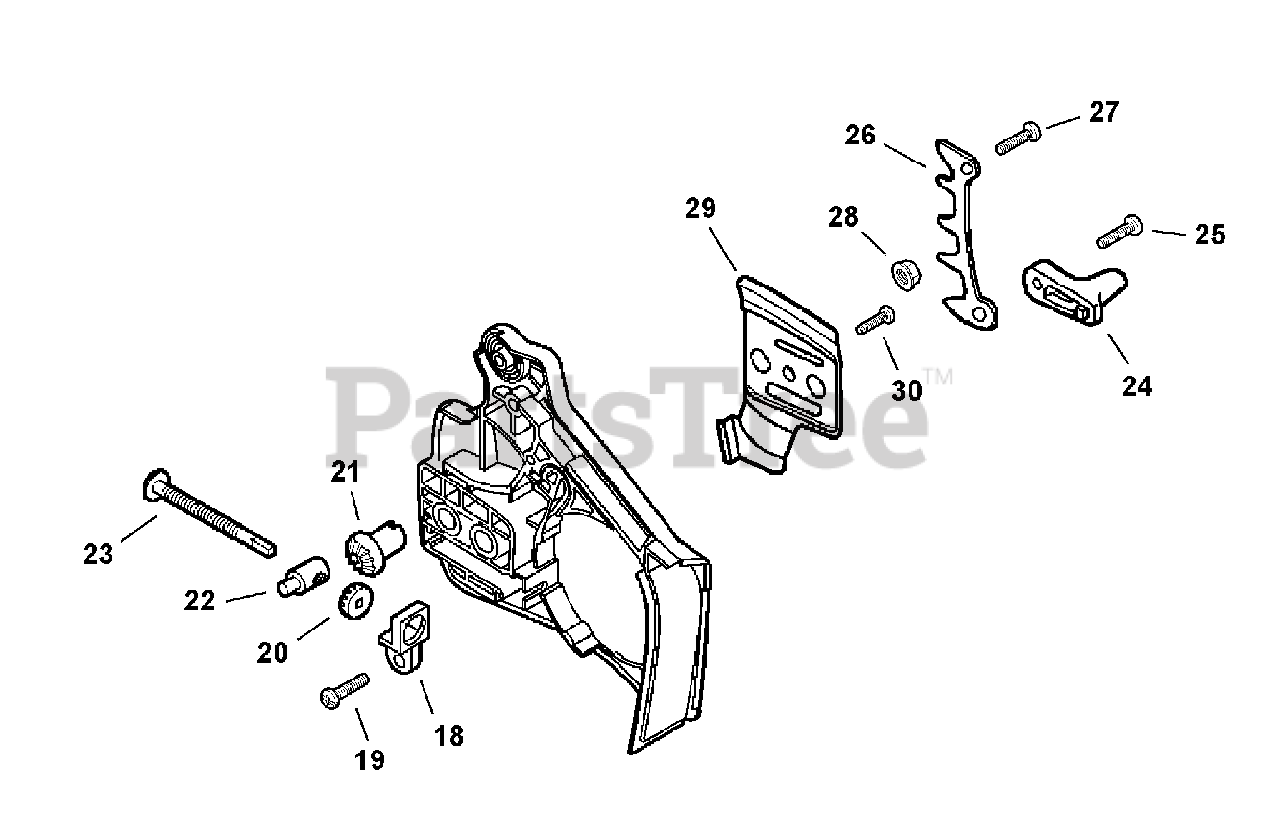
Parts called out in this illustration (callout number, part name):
18	COLLAR 8
19	SCREW 4×12
20	GEAR, BEVEL
21	GEAR, BEVEL
22	TENSIONER, CHAIN
24	CHAIN CATCHER
25	SCREW, TAPPING 5×20
26	SPIKE, BUMPER
27	SCREW, TAPPING 5×20
28	NUT, FLANGE M6
29	PLATE, GUIDE - INNER
30	SCREW 4×10
